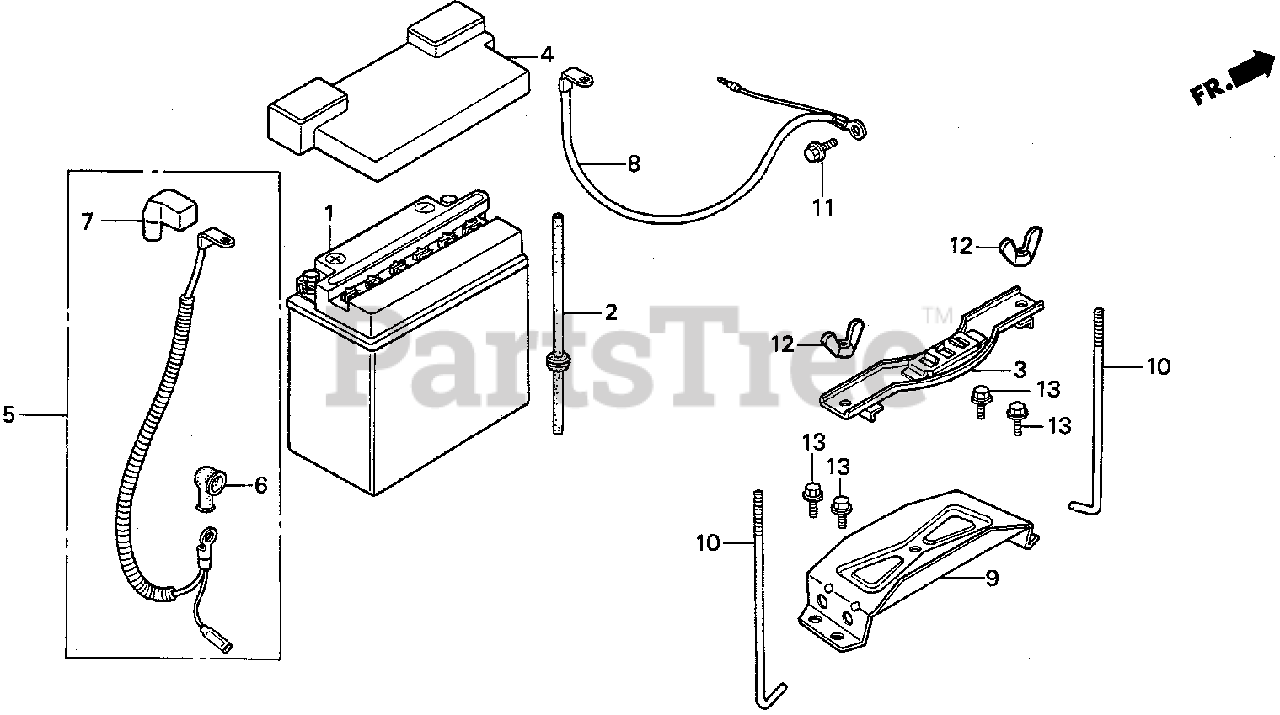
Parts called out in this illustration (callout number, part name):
1	BATTERY (YB18L-A) (YUASA)
1	BATTERY ASSY. (12V18A)
2	TUBE, BATTERY BREATHER
3	PLATE, BATTERY SETTING
4	COVER, BATTERY
5	CABLE ASSY., STARTER
6	COVER, STARTER MOTOR TERMINAL
7	COVER, BATTERY TERMINAL
8	CABLE ASSY., GROUND
9	BASE, BATTERY
10	BOLT, BATTERY SETTING
11	BOLT, FLANGE (6X12) (CT200)
12	NUT, TOOL BOX SETTING
13	BOLT, FLANGE (6X12)
